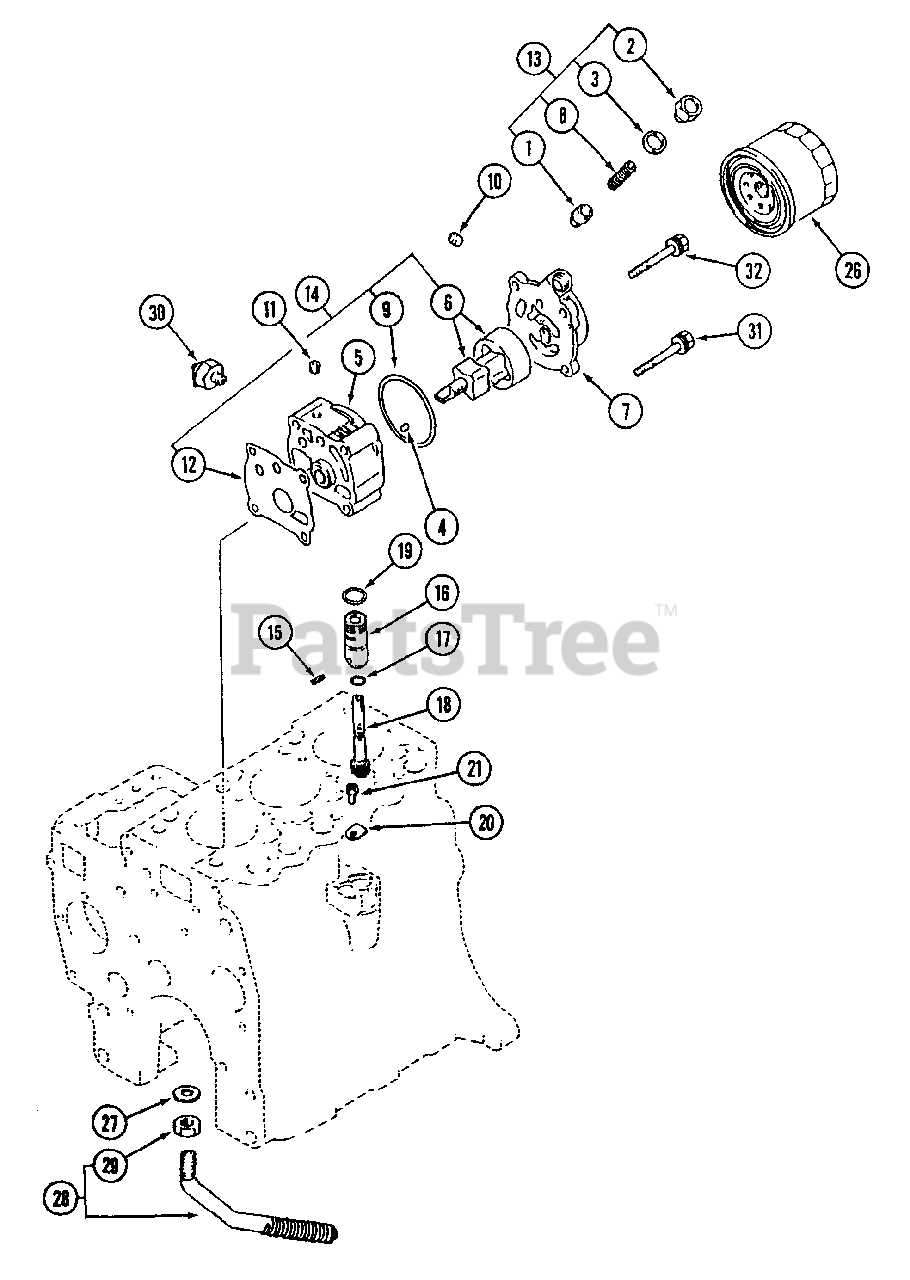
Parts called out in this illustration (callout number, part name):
1	Plunger, Relief
3	Gasket, Oil Drain Plug
4	Pin, Dowel
5	Body, Oil Pump
6	Rotor Ass'y.
7	Cover, Oil Pump
8	Spring, Relief
10	Plug, Taper
11	Plug, Taper
12	Gasket, Oil Pump
13	Service Kit, Relief Valve
14	Service Kit, Rotor
15	Pin, Spring
16	Sleeve, Speedometer Gear
18	Gear, Speedometer Driven
20	Plate, Locking
21	Bolt, w/Washer
26	Oil Filter Ass'y.
28	Oil Screen Ass'y.
30	Oil Pressure Switch Ass'y.
31	Bolt. Washer Ass'y.
32	Bolt, Washer Ass'y.
